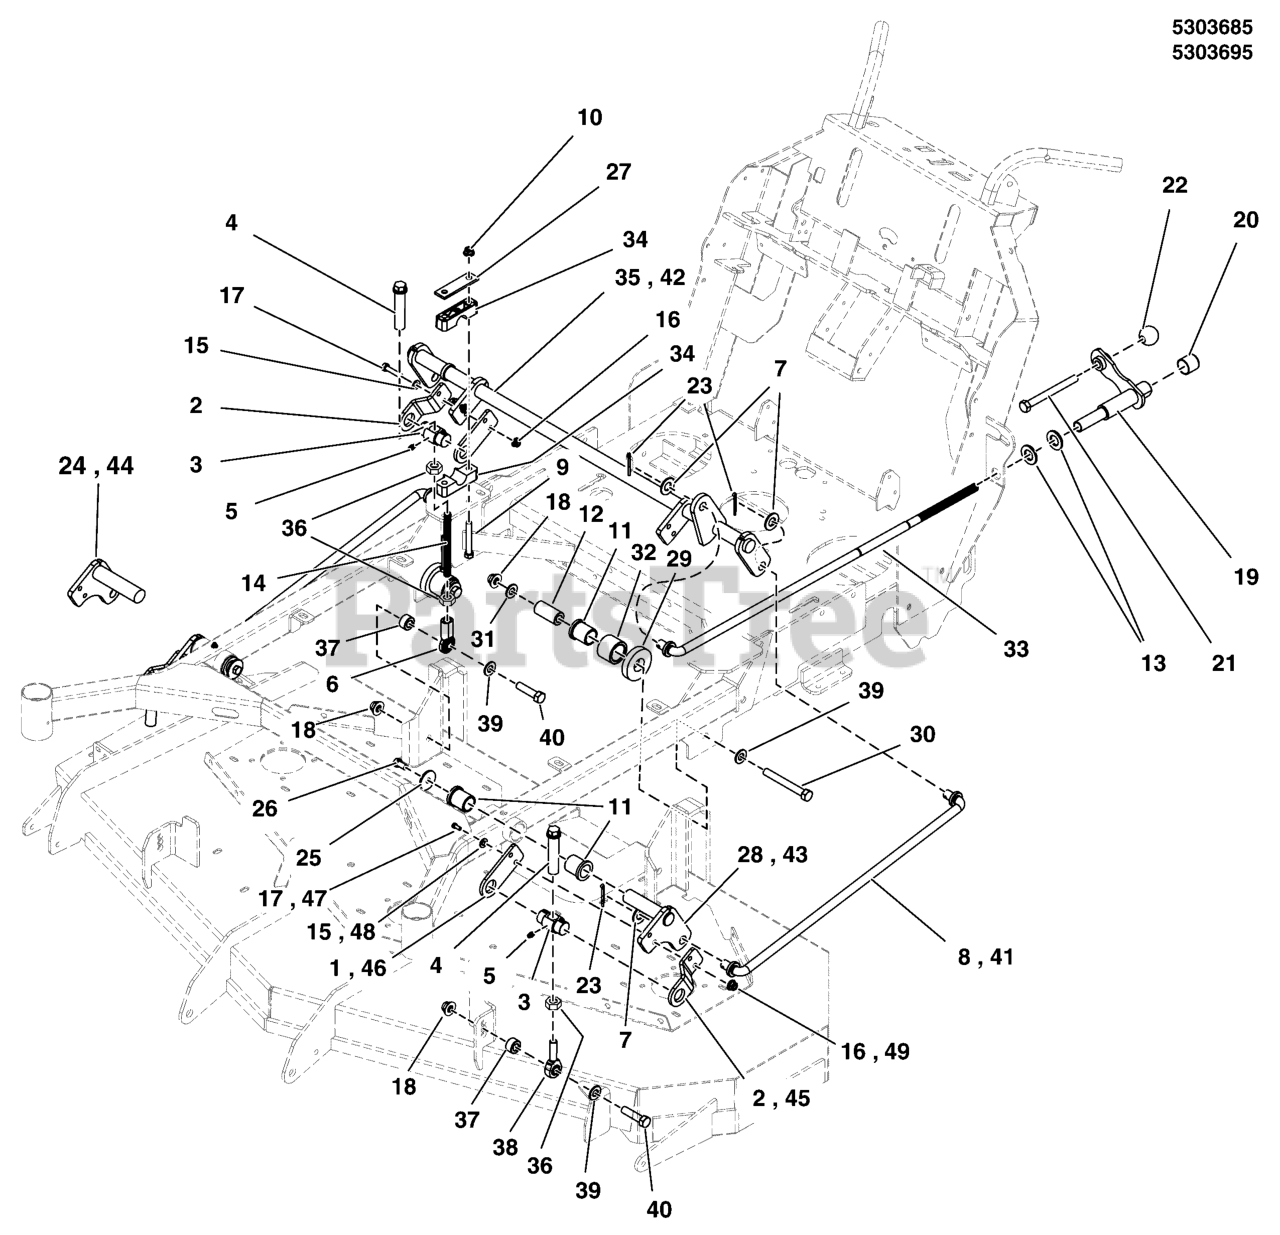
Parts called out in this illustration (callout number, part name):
1	BRACKET, INNER TRUNION MOUNT - BLK
2	BRACKET, OUTER TRUNION MOUNT - BLK
3	PIVOT, DECK LIFT TRUNION, GREASABLE
4	ADJUSTER, HEIGHT
5	GREASE FITTING, 1/4-28 STRAIGHT
6	JOINT-BALL .500-20 THD .500ID, CLR ZINC
7	WASHER, 5/8 SAE
8	ROD, DECK LIFT TIMING, 61
9	BOLT, 3/8-16 X 2-3/4" GD5 CZ
10	NUT, 3/8-16 HEX NYLOCK FLANGE
11	BUSHING, FLANGE
12	SPACER, .52 X 1.00 X 2.09 - SS
13	WASHER, 3/4 SAE
14	ROD, 1/2-20 X 5.50 TFL, CZ
15	WASHER, 5/16" SAE
16	NUT, 5/16-18 HEX NYLOCK FLANGE
17	BOLT, 5/16-18, GD5 CZ
18	NUT, Hex Flange, Nylock, 1/2-13
19	DECK CRANK, SW30 - BLK
20	CAP, VINYL, 1.062 X 1.00 BLK
21	BOLT-1/2-13 X 5 GD5 CZ
22	KNOB, PLASTIC, 1/2-13
23	PIN, COTTER, 1/8 X 1-1/4
24	WELD, DECK LIFT LEVER, RH - BLK
25	WASHER, .390 X 1.50 X .109, YZ
26	BOLT, 3/8-16 X 3/4, PLT W/PATCH
27	PLATE, PIVOT BLOCK SUPPORT - BLK
28	WELD, DECK LIFT LEVER, LH - BLK
29	WASHER, FRICTION
30	BOLT, 1/2-13 X 3-1/4, HEX HD, GD5, CZ (SV)
31	WASHER, 1/2 USS
32	ROLLER, DECK HEIGHT
33	ROD, DECK HEIGHT
34	PIVOT BLOCK, PLASTIC
35	WELD, SHAFT, DECK LIFT, SW35 - BLK
36	NUT, 1/2-20 HEX JAM
37	WASHER, .515 X 1.00 X .25", CZ
38	BALL JOINT, 1/2-20, RH, MALE, METAL RACE
39	WASHER, 1/2 SAE
40	BOLT, 1/2-13 X 2" GD5 CZ
41	ROD, DECK LIFT TIMING, 48-52
42	WELD, SHAFT, DECK LIFT, SW35 - BLK
43	WELD, DECK LIFT LEVER, LH - BLK
44	WELD, DECK LIFT LEVER, RH - BLK
45	BRACKET, OUTER TRUNION MNT - BLK
46	BRACKET, INNER TRUNION MNT - BLK
47	BOLT, 3/8-16 X 1-1/2" GD5 CZ
48	WASHER, 3/8 SAE
49	NUT, 3/8-16 HEX NYLOCK FLANGE
